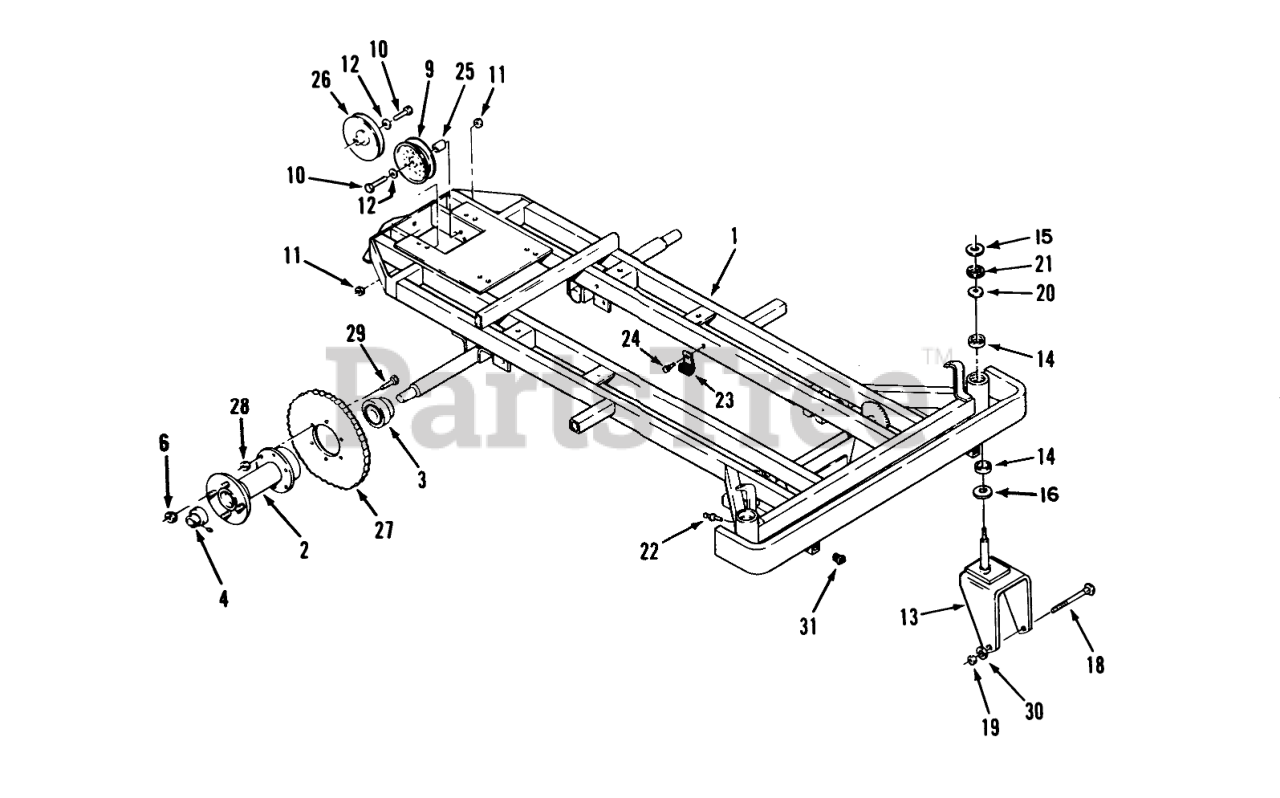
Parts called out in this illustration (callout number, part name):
1	WLDMT-FRAME B
2	Hub-Rear Wheel (Incl. Ref.# 22)
3	BEARING-REAR AXLE
4	BEARING-REAR AXLE
6	NUT-LUG
9	PULLEY FLAT B
10	SCREW-HH
11	NUT-LOCK, NI
12	WASHER-FLAT
13	Fork-Front Wheel
14	BUSHING PIVOT
15	RING-RETAINING
16	WASHER-THRUST
18	SCREW-HH
19	NUT-HEX
21	WASHER-THRUST
22	FITTING-GREASE
23	CLIP
24	SCREW-HWH
25	BUSHING
26	PULLEY-IDLER V
27	SPROCKET-REAR HUB B
28	NUT-LOCK, NI
29	SCREW-HH
30	WASHER-LOCK
31	PLUG-SQUARE PLASTIC
